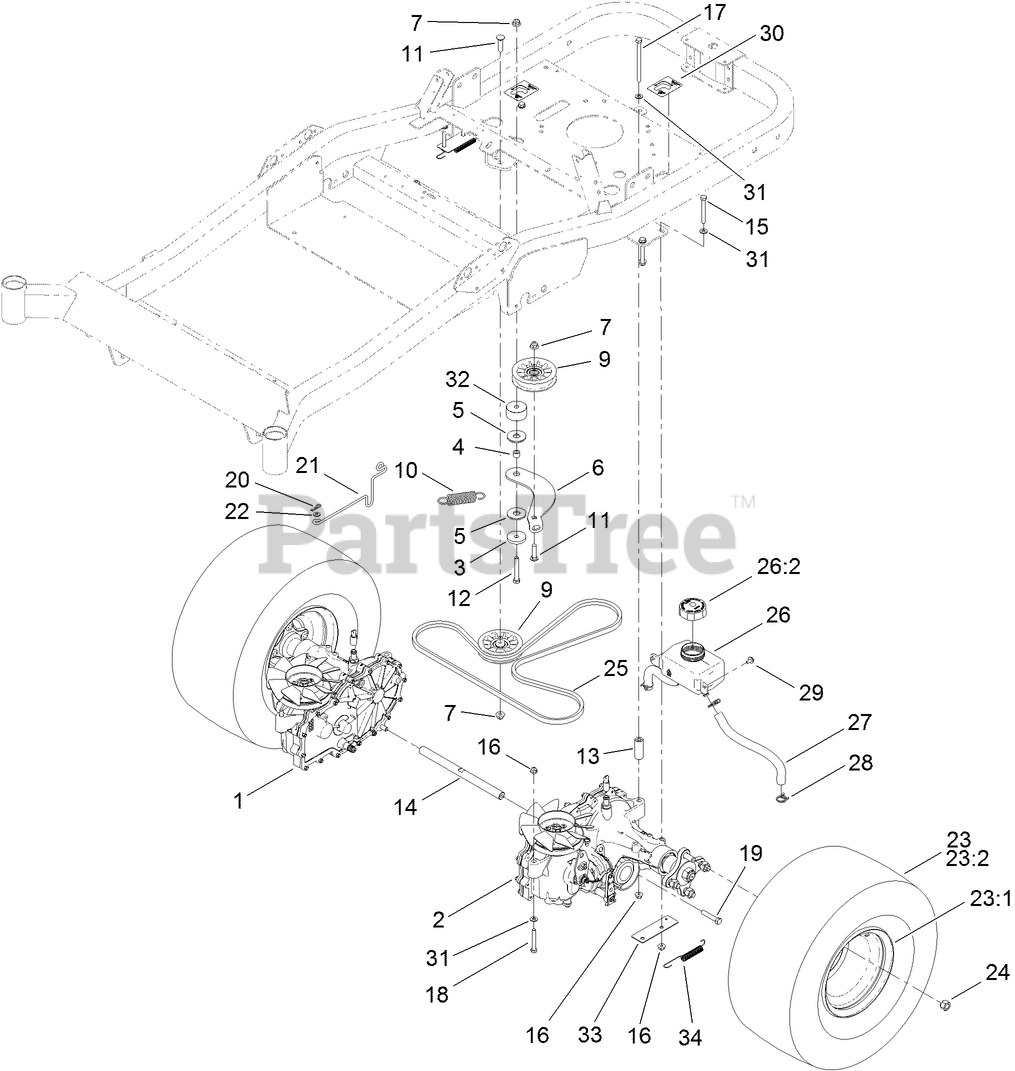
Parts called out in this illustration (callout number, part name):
1	RH HYDRO TRANSMISSION ASM
2	LH HYDRO TRANSMISSION ASM
3	WASHER-PLAIN
4	SPACER
5	WASHER-FRICTION, COMPOSITE
6	ARM-IDLER
7	NUT-HF, NI
9	PULLEY-IDLER, FLAT
10	SPRING-EXTENSION
11	SCREW-CARR
12	SCREW-HH
13	SPACER-HYDRO
14	SHAFT-CROSS, HYDRO
15	SCREW-HH
16	NUT-HF, NI
17	SCREW-HH
18	SCREW-HH
19	SCREW-HH
20	PIN-COTTER
22	WASHER-FLAT
23	WHEEL AND TIRE ASM
24	NUT-LUG
25	V-BELT
26	HYD RESERVIOR ASM
26:2	CAP-RESERVOIR, HYD
27	HOSE-OVERFLOW
28	CLAMP-HOSE
29	SCREW-HHFTF
30	DECAL-BYPASS
31	WASHER-PLAIN
32	SPACER
33	PLATE-SPRING
34	SPRING-EXTENSION
